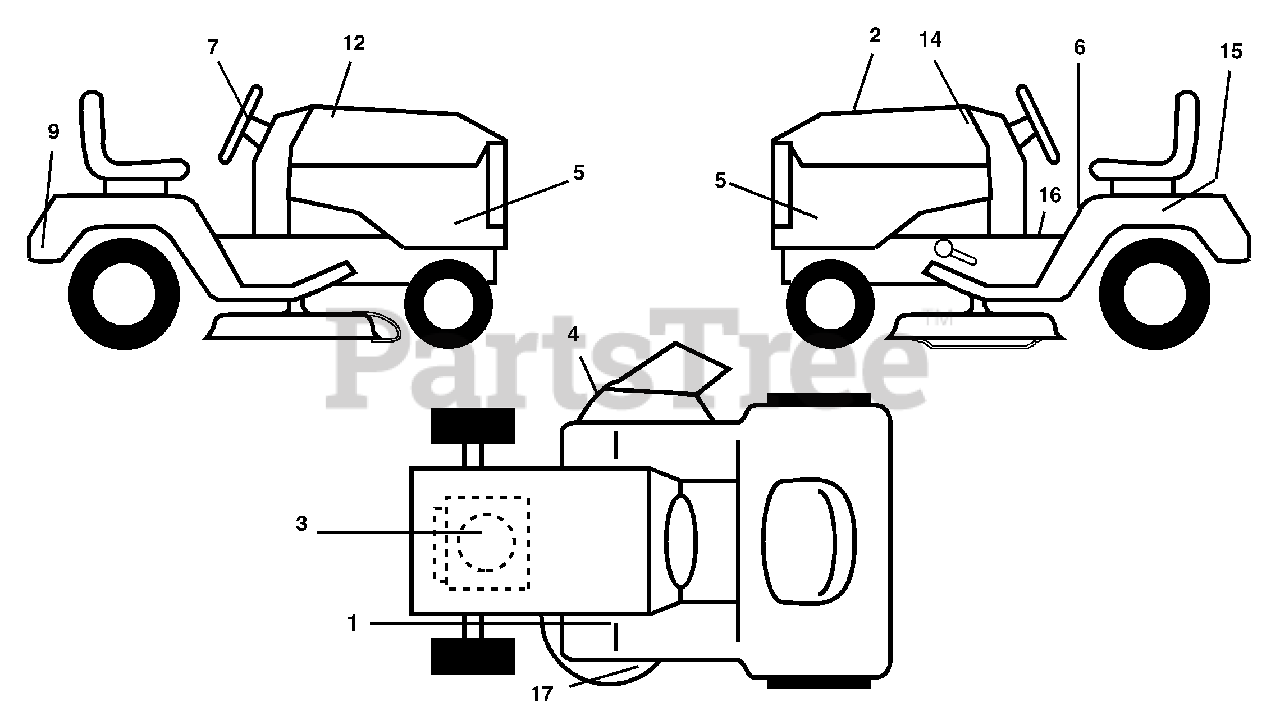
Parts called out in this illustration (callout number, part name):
1	Decal, Clutch/Brake Eng/Fr
2	Decal, Replacement
3	Decal, Engine HP
4	Decal, Warning
5	Decal, SDPNL
6	Decal, Fender Danger English
7	Decal, Ins Str Wh
9	Decal, Fender
12	Decal, Hood RH
14	Decal, Hood LH
15	Decal, Caution, Battery
16	Decal, Oper Sdl P/L Gear Dr Eng
17	Decal, V-Belt Sch.
